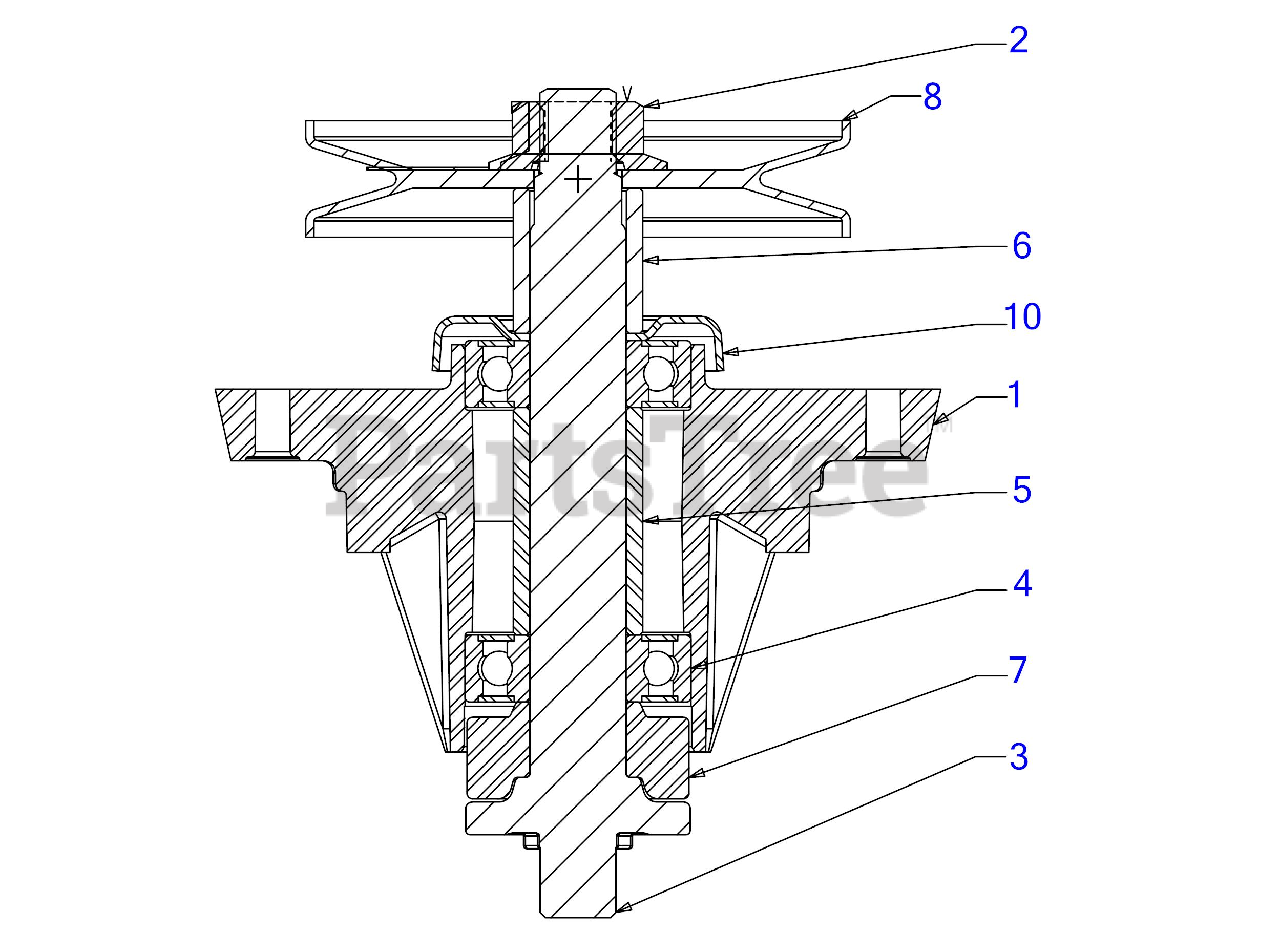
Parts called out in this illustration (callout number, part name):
1	DECK SPINDLE HOUSING
2	FLANGE NUT 5/8-18
3	BLADE SPINDLE SHAFT STAR 6.11 LG
4	BALL BEARING
5	SPACER- .792 x 1.060 x 1.860
6	SPACER .792 x 1.060 x 1.191
10	SHIELD-BRG DECK
